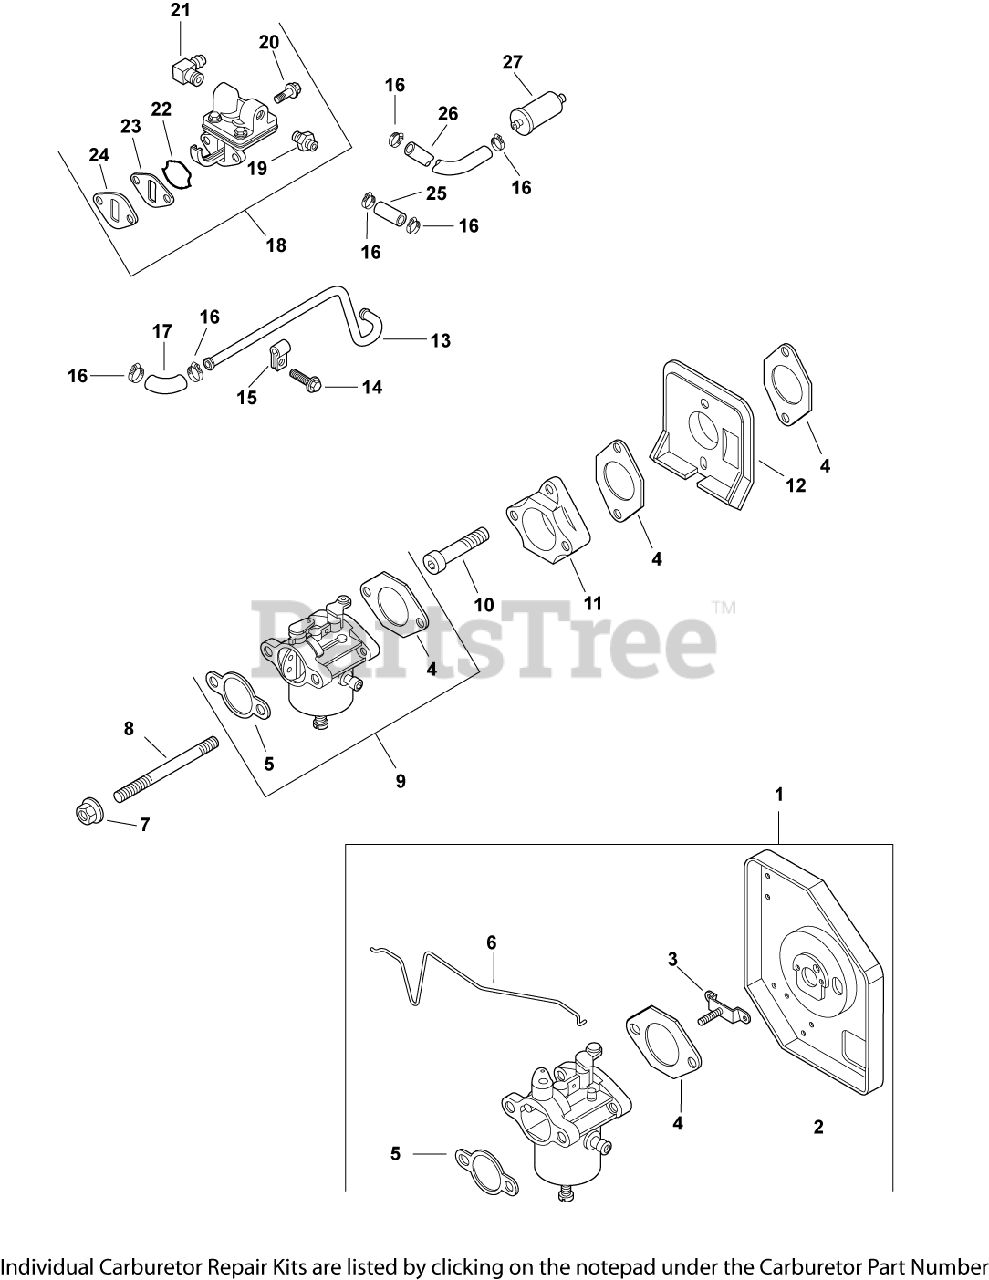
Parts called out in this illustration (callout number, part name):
1	KIT, CARB. RETROFIT
2	BASE, AIR CLEANER
3	BRACKET, AIR CLEANER
4	GASKET, CARBURETOR
5	GASKET, AIR CLEANER BASE
6	LINKAGE, CHOKE
7	NUT, FLG M6X1.0
8	STUD,M6X1.0X116
9	KIT, CARBURETOR
10	SCREW, SKT CAP M6X1.0X35
11	ADAPTER, CARBURETOR
12	DEFLECTOR, HEAT
13	LINE, FUEL - DISCONTINUED
14	SCREW, FLG THD FRM M5X.8X10
16	CLAMP, HOSE (KM)-USE 25 237 31-S
17	HOSE, FUEL LOW-PERMEATION
18	KIT, FUEL PUMP
19	KIT, STRAIGHT FITTING
20	SCREW,FLG THD FRM M6X1.0X20-(#25086396S)
21	CONNECTOR, 90 DEG. HOSE
22	O-RING, FUEL PUMP
23	SPACER, FUEL PUMP
24	GASKET, FUEL PUMP
25	LINE - DISCONTINUED
26	LINE, FUEL 2" PUMP-FILTER
27	FILTR,FUEL 75 MICRON (GRAVTY FEED)
